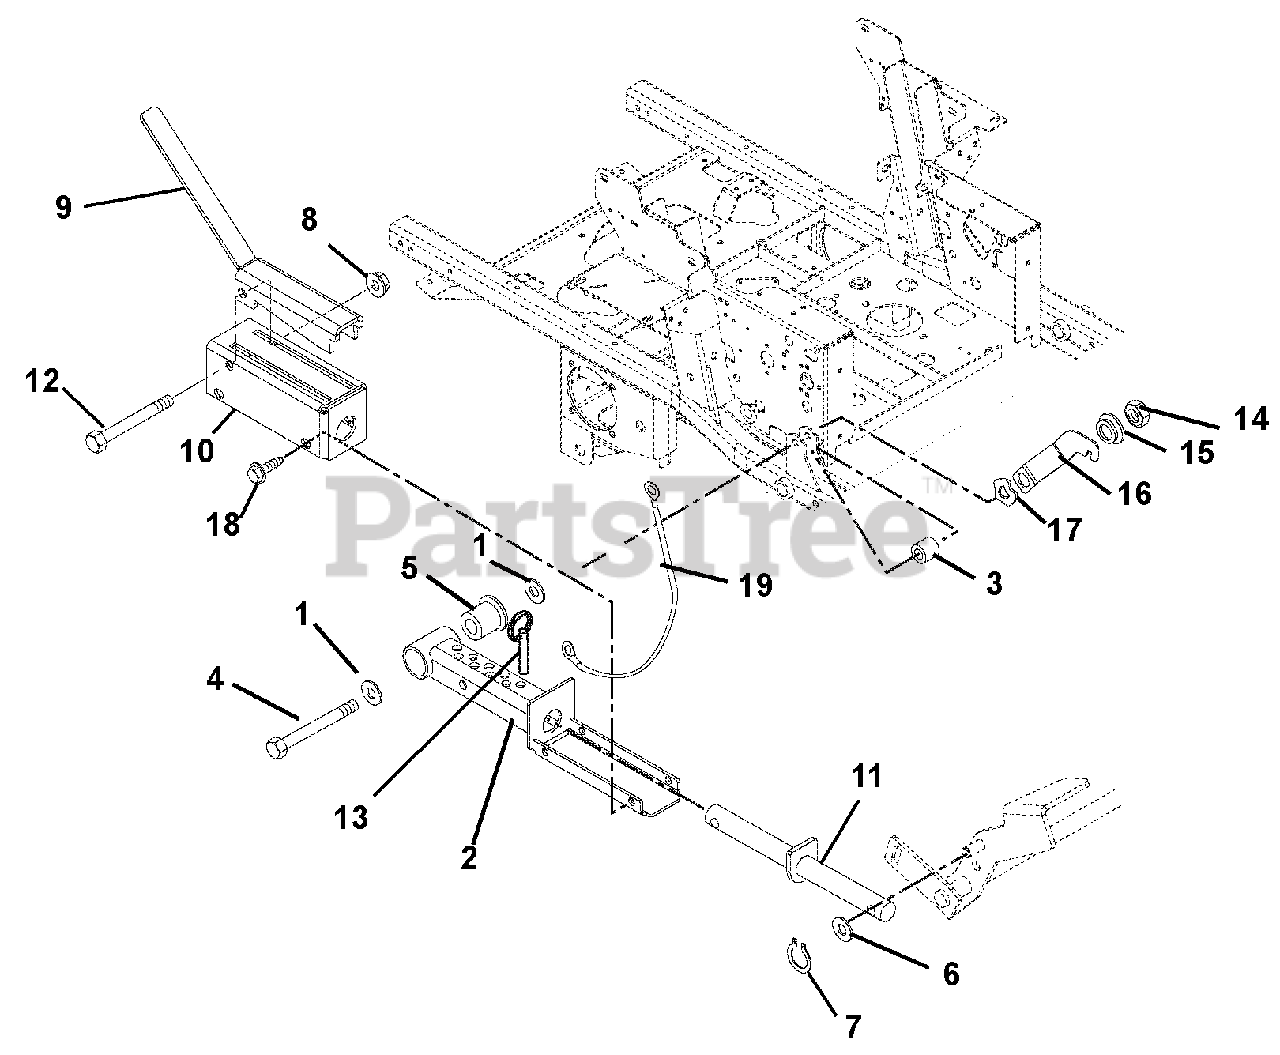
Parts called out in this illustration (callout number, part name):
1	Washer, Flat Steel .531 x 1.250 x .10
2	Weldment, Mechanical Lift
3	Bushing .516 x 1.00 x 1.05
4	Bolt, Hex .50-13 x 5.00 Grade 5
5	Bearing, Pedestal Powdered Metal
6	Washer, Flat Steel .656 x 1.310 x .095
7	Ring, Retaining External .625 x .050
8	Nut, Locking Top Flange .38-16
9	Lock-Up, Mechanical Lift
10	Weldment, Mechanical Lift Cover
11	Weldment, Mechanical Lift Shaft
12	Bolt, Hex .38-16 x 3.25 Grade 5
13	Pin, Spring Ball .375 O.D. x 1.50
14	Nut, Locking Top Flange .50-13
15	Bushing, Flange .515 x .75 x .275 x 1.12
16	Latch, Footboard
17	Washer, Wave .076 x 1.12 x .08
18	Screw, Tapping .38-16 x .50
19	Cable, 12.0 Lanyard, Nylon
